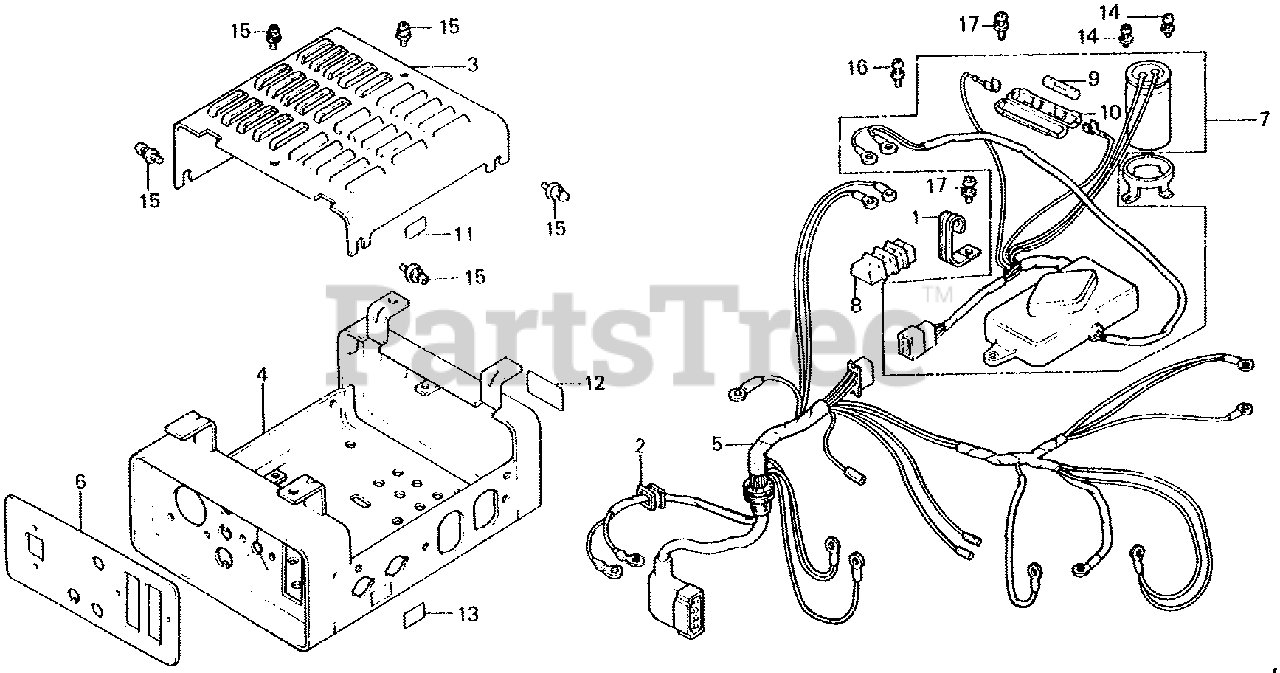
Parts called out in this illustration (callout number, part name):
1	CLAMP A, WIRE
2	BUSH, RUBBER
3	COVER, CONTROL BOX (UPPER) *R8* (BRIGHT RED)
4	COVER, CONTROL BOX (LOWER) *R8* (BRIGHT RED)
5	WIRE HARNESS ASSY.
6	PANEL, FR.
7	REGULATOR ASSY., AUTOMATIC VOLTAGE
7	REGULATOR ASSY., AUTOMATIC VOLTAGE (NOT AVAILABLE)
8	TERMINAL (2 POLE)
9	FUSE (2.5A)
10	HOLDER, FUSE
11	MARK C, CAUTION (NOT AVAILABLE)
12	MARK, GROUND
13	MARK B, D.C. OUTPUT
14	SCREW-WASHER (4X6)
15	SCREW-WASHER (4X6)
16	SCREW-WASHER (4X16)
17	SCREW-WASHER (5X10)
17	SCREW-WASHER (5X16)
